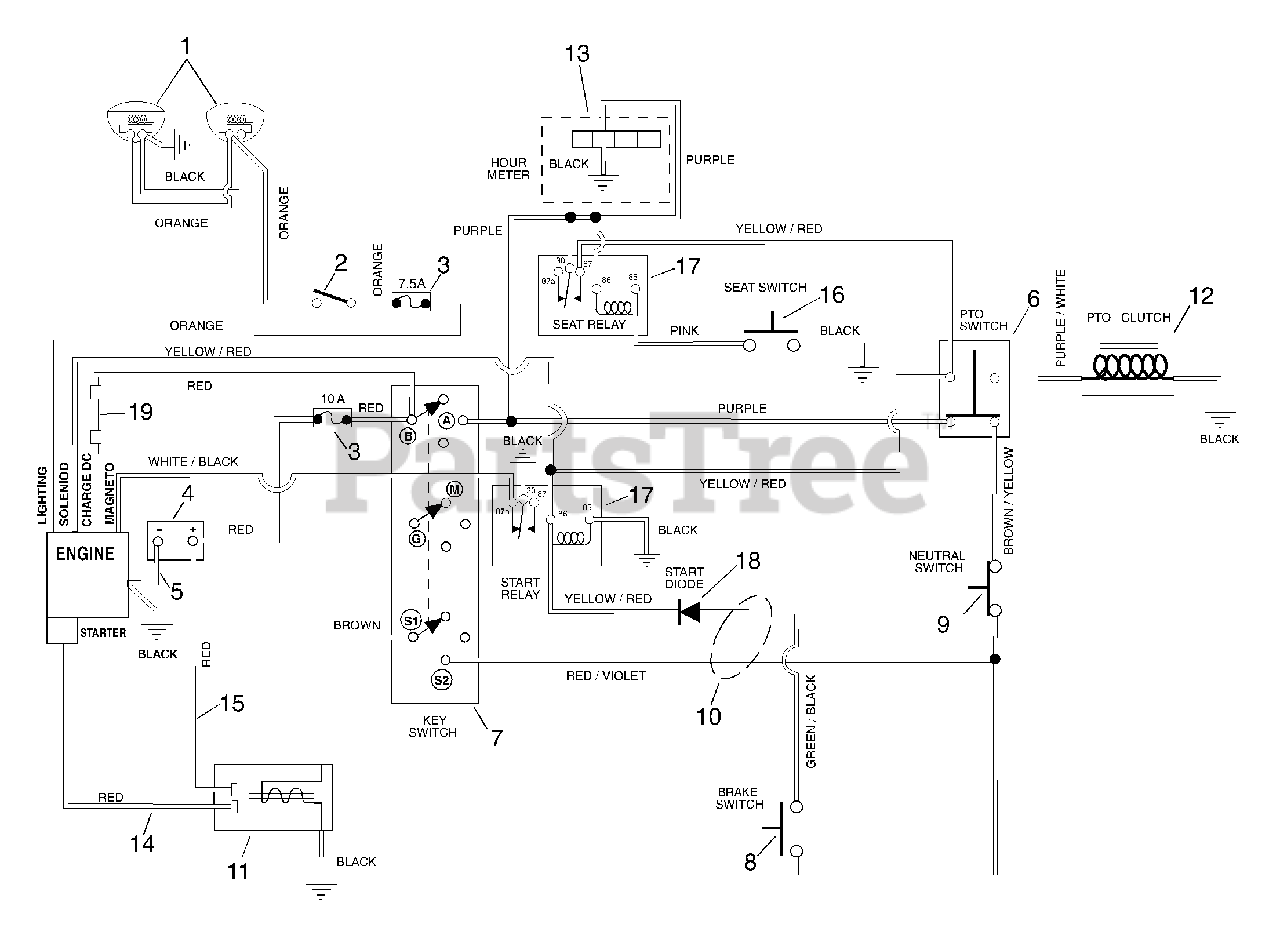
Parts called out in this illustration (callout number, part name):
1	HEADLIGHT- RH
1	HEADLIGHT- LH
2	SWITCH - LIGHT
3	7.5 AMP Fuse
3	10 AMP Fuse
4	BATTERY W/TUBE
5	GROUND CABLE .31X22.00X.31
6	PTO KNOB/ SWITCH ASSY
7	KEY SWITCH
8	SWITCH- SINGLE POLE N.O.
9	SWITCH, NEUTRAL START N.C.
10	WIRE HARNESS - 1440G B&S
11	SOLENOID
12	ELECTRIC CLUTCH/BRAKE(1.8AMP)
13	HOURMETER KIT- SIERRA
14	START CABLE 22"
15	STARTER CABLE 6.75"
16	SWITCH- SEAT
17	RELAY
18	MOLDED DIODE PLUG 1 AMP
19	WIRE HARNESS ADAPTOR (BRIGGS)
